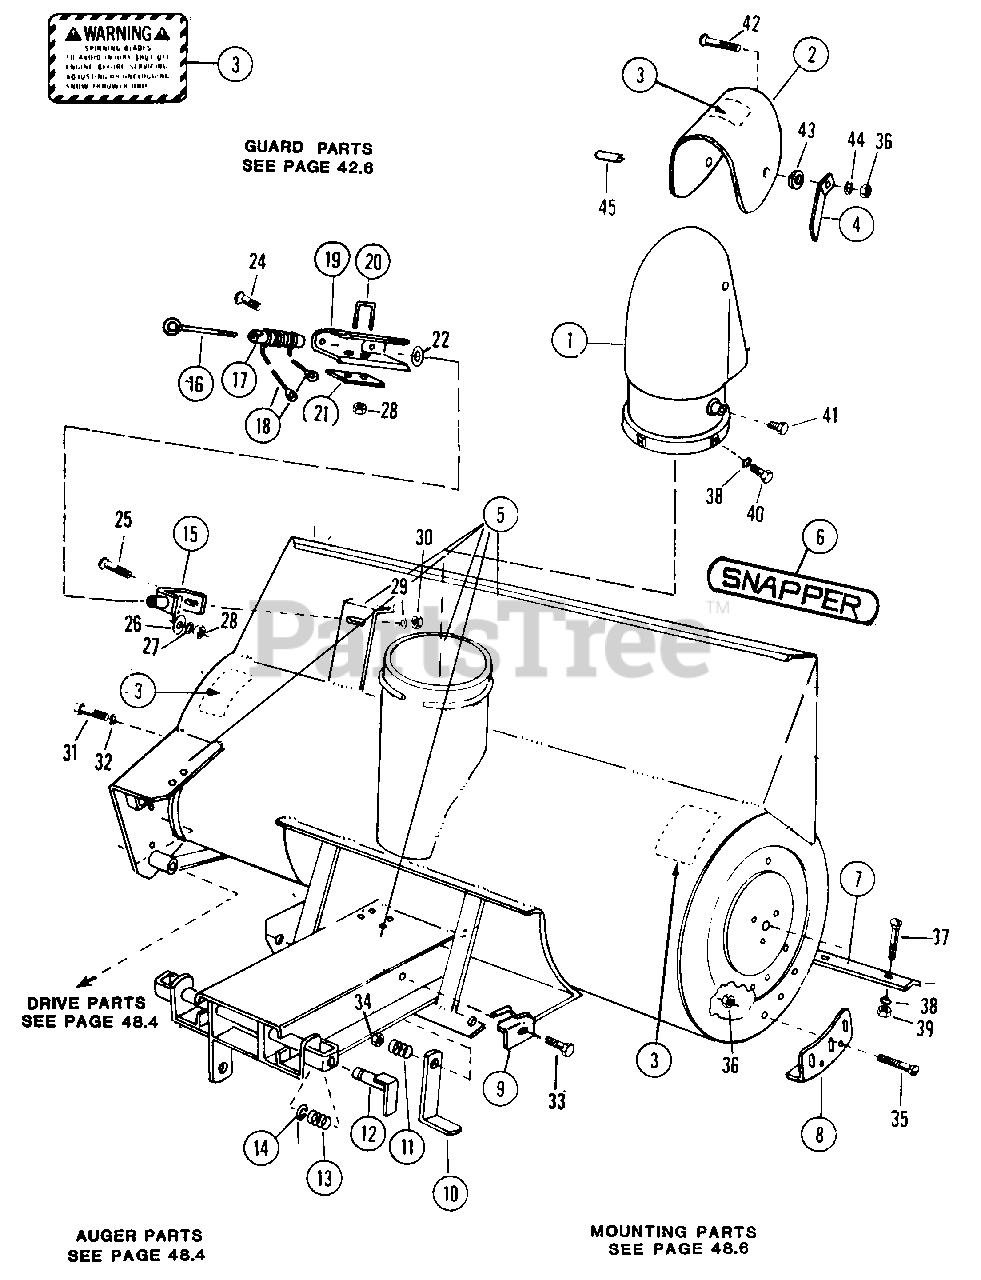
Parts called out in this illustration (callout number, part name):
1	CHUTE, DISCHARGE
2	DEFLECTOR
3	DECAL, WARNING (SPINNING BLADES)
4	STRAP, DEFLECTOR LOCKING
5	HEADER, 48" SNOWTHROWER
6	DECAL, SNAPPER
7	BLADE, SCRAPER
8	SHOE, SKID
9	BRACKET, DOWN-STOP
10	KICKSTAND
11	SPRING, KICKSTAND
12	PIN, QUICK COUPLER
13	SPRING, COUPLER
14	RING, PIN RETAINING
15	BRACKET, CHUTE DRIVE
16	EYE-BOLT, CHUTE DRIVE
17	TUBE, CHUTE DRIVE
18	CABLE, CHUTE DRIVE
19	SHROUD, CHUTE DRIVE
20	U-BOLT, LEVEL WIND
21	STRAP, LEVEL WIND FRICTION
22	WASHER, STACK CONTROL
24	BOLT, 3/8C x 3/4 CARRIAGE
25	BOLT, 3/8C x 1 CARRIAGE
26	WASHER, 3/8" FLAT
27	LOCKWASHER, 3/8"
28	NUT, 3/8C HEX
29	WASHER, 3/8" Flat
30	LOCK NUT, 3/8C HEX
31	BOLT, 1/2C x 1-1/4 HEX HEAD
32	LOCKWASHER, 1/2"
33	BOLT, 3/8C x 2 HEX HEAD
34	LOCKNUT, 3/8C HEX
35	BOLT, 5/16C x 3/4 CARRIAGE
36	LOCKNUT, 5/16C (CENTER NYLON)
37	BOLT, 1/4C x 5/8 CARRIAGE
38	LOCKWASHER, 1/4"
39	NUT, 1/4C HEX
40	BOLT, 1/4C x 5/8 HEX HEAD
41	BOLT, 1/4C x 1/2 HEX HEAD
42	BOLT, 5/16C x 1" CARRIAGE
43	WASHER, 13/32 x 1-1/2
44	LOCKWASHER, 3/8 INTERNAL TOOTH
45	PAD, DEFLECTOR
